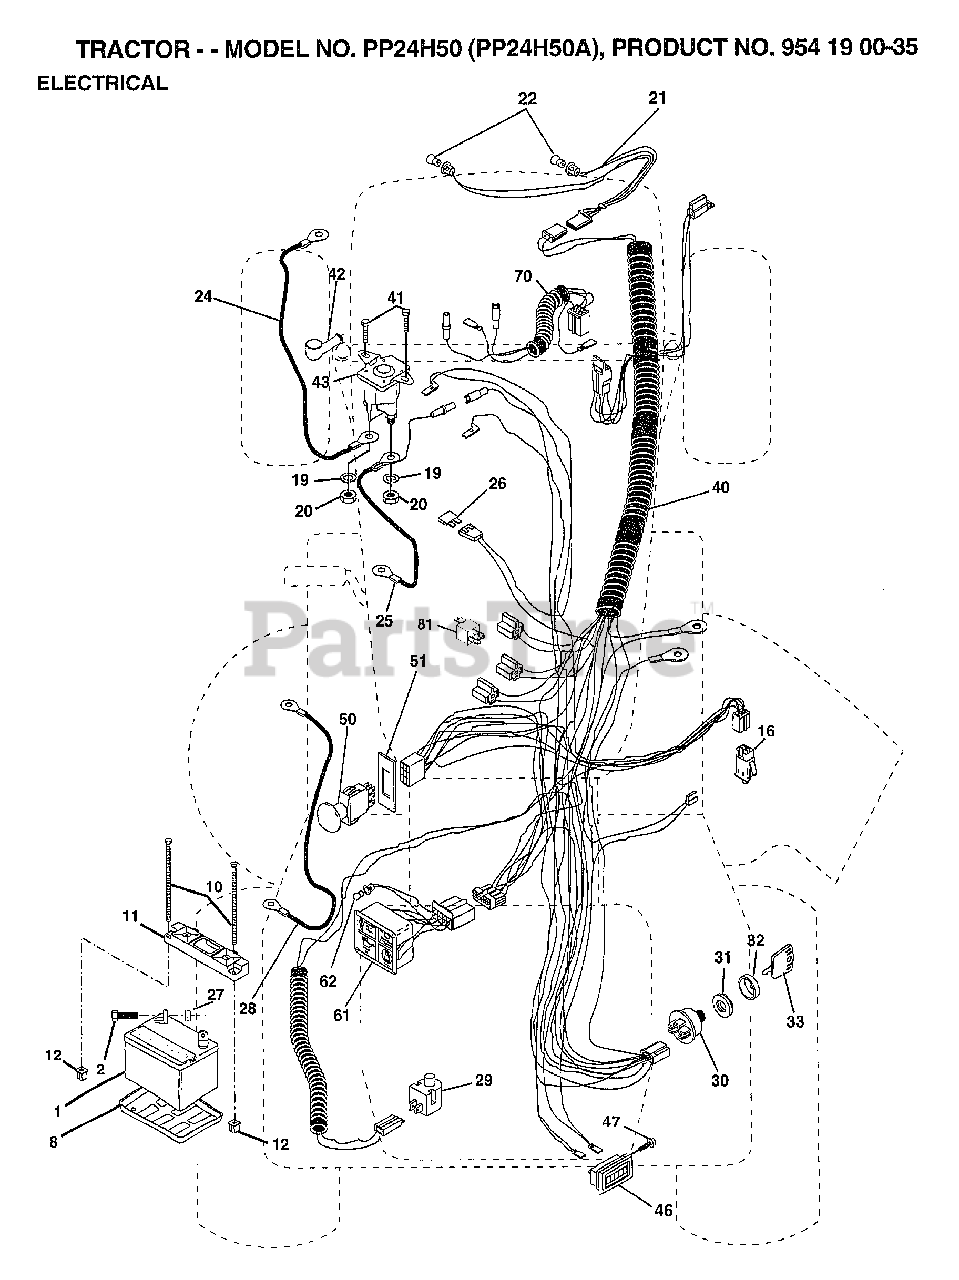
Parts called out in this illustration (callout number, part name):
2	BOLT LT
8	"TRAY T, BATTERY"
11	HOLDDOWN BATTERY
20	NUT
21	HARNESS.ASM.LIGHT W/4152J
22	HEADLAMP BULB
24	CABLE.6GA.12.5.
25	CABLE-BATTERY T
26	FUSE HYT
27	NUT
28	CABLE T
29	SWITCH.PLUNGER
30	SWITCH.IGN.
31	NUT IGNITION
32	COVER KEY SWITCH
33	KEY MLD GEN DELTA
40	HARNESS IGN
41	SCREW
46	HOUR METER T
47	SCREW
50	PTO SWITCH.BLK
51	RING RETAIN PTO
61	LIGHT.PKG.ASM.
62	BULB LIGHT T
81	RELAY ASSY T
